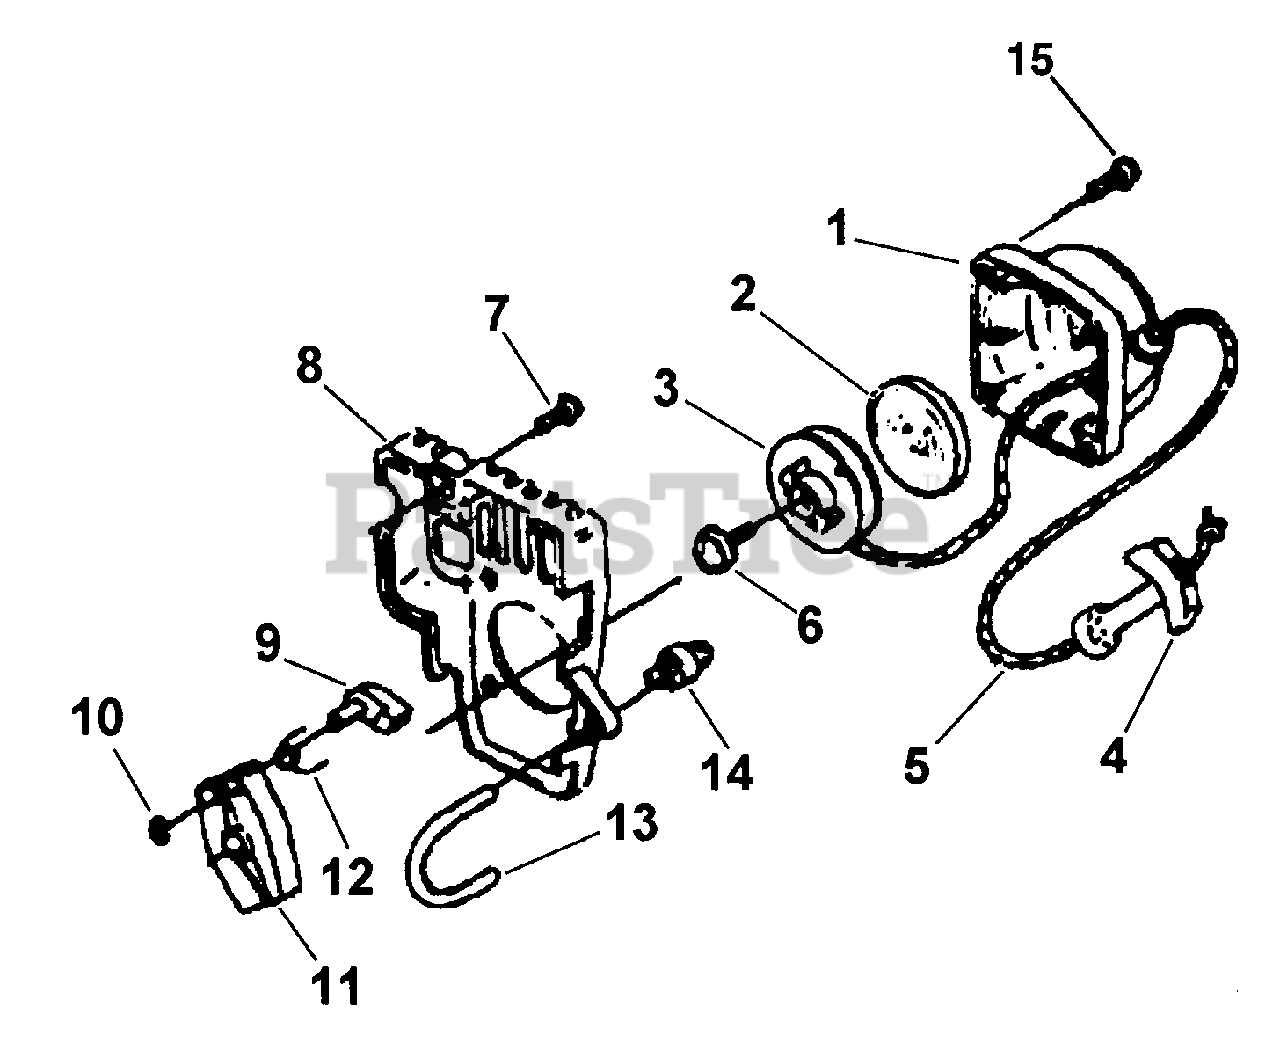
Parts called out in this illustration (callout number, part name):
1	STARTER ASSY
2	SPRING, RECOIL
3	PULLEY, STARTER
4	GRIP, STARTER
5	ROPE, STARTER
6	SCREW
7	SCREW
8	COWLING, ENGINE
9	PAWL, STARTER
10	RING, RETAINING
11	CUP, STARTER
12	SPRING, STARTER
13	TUBING, PRIMER LINE 8"
14	BULB, PRIMER
15	SCREW, TAPTITE 10-24 X 3/4
